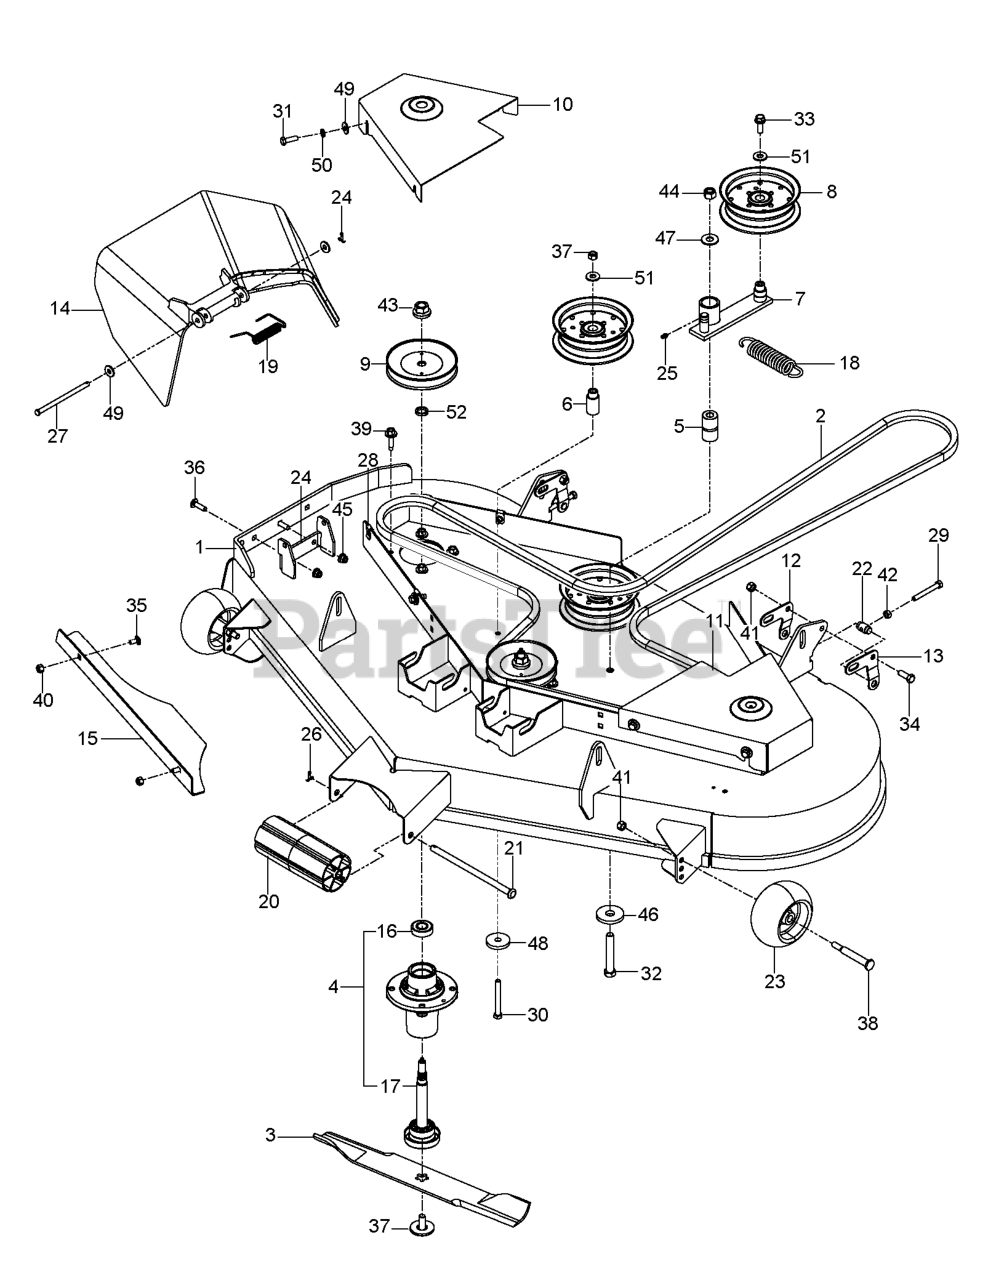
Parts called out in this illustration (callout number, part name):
1	DECK SVC MZT 52 W/DECALS.ORNG
2	BELT, B, 148.5
3	BLADE, 18"
4	MANDREL.DECK.ASSEMBLY
5	PIVOT BUSHING
6	IDLER BUSHING
8	PULLEY, IDLER
9	PULLEY MANDREL
10	BELT SHIELD, RIGHT 52, ORG
11	BELT SHIELD, LEFT 52, ORG
12	BRACKET.RT.PNT.MS431
13	BRACKET.LH.PNT.MS431
14	DISCHARGE CHUTE 52"
15	CONFINEMENT PLATE, 52"
17	SHAFT ASM MANDREL
19	SPRING - TORSION
20	NOSE ROLLER 48"
21	ROD.ROLLER.NOSE.NARROW.48"
22	TRUNION, PITCH
23	GAUGE WHEEL
24	BRACKET MZ CHUTE
25	ZERK
26	RP_COTTER PIN 1/8 X 3/4
27	PIN-CLEVIS 5/16 DIA X 5.19 ZD
28	U-CLIP 5/16-18 NUT RETAINER
29	HCS 5/16-18 X 2 1/2 TPBLT
30	BOLT.HEX.FIN.3/8-16 X 3.GR5
31	BOLT.FIN.HEX.5/16-18UNC X 1.00
32	HCS 1/2C X 3 1/4
33	4CS 3/8C X 1 SERRATED HEAD
34	HCS 3/8-16X1.GRD.5.ZD
35	BOLT.CARR.5/16-18X5/8.SHORT
37	BLADE BOLT ASSY-7/16" TB REPL
38	BOLT, SHOULDER
39	BOLT.HEX.WASHR.HED.313-18X1.19
40	NUT.71038.31-18.HEX.NYLOCK
41	NUT 3/8-16 NYLOC
42	NUT 5/16C HEX
43	LOCKNUT - 9/16
44	NUT 1/2-13 HEX NYLOC ZD
45	5/16-18 NYLOC FLANGE NUT
46	WASHER, SUPPORT
47	WASHER 1/2 FLAT
48	SPINDLE WASHER
49	WASHER.5/16.FLAT.STE.STD.
50	WASH.5/16.SLW.ZD
51	RP WASHER 3/8 FLAT
52	WASHER-SPACER
